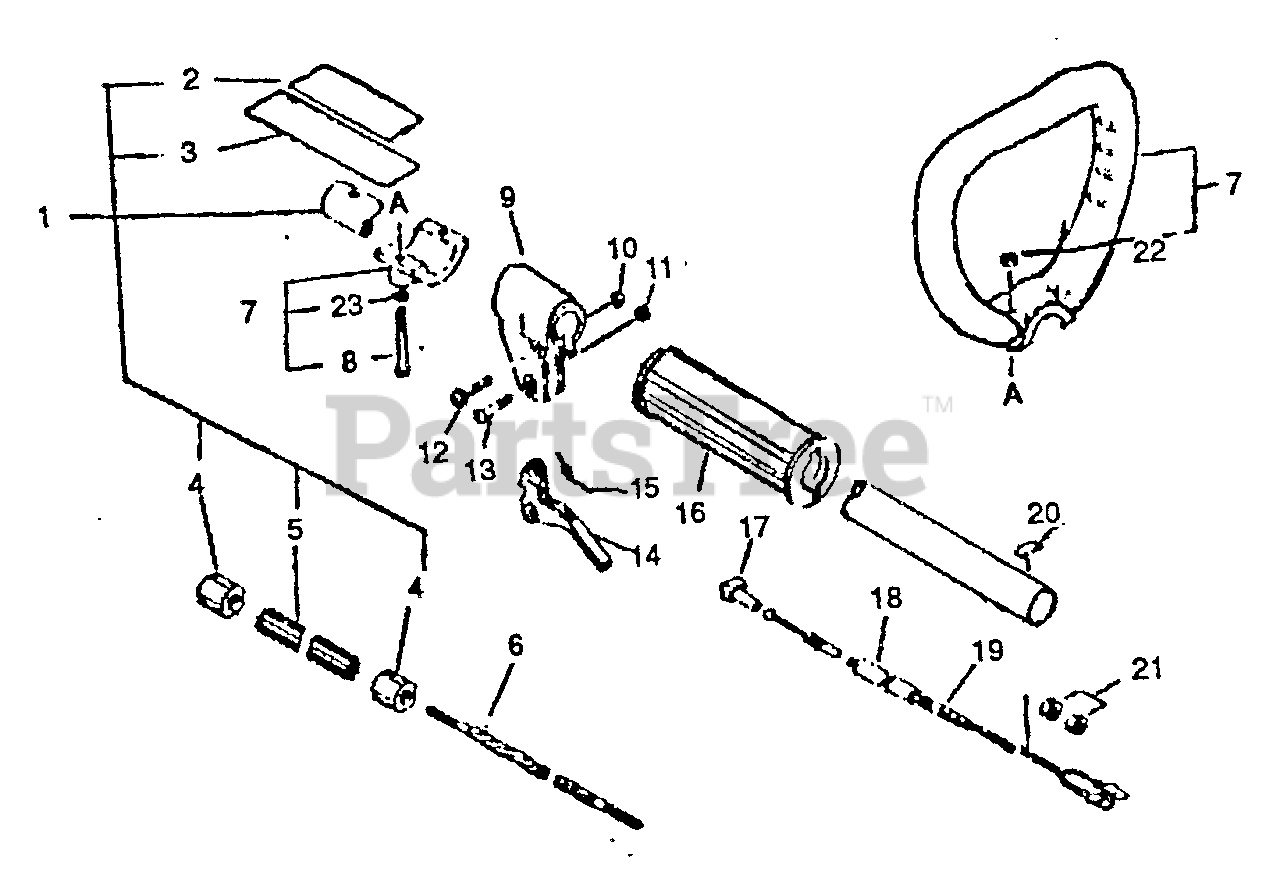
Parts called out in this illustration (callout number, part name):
1	Housing Asy, Driveshaft
2	Label, Caution
3	Label, Caution
5	Liner, Flexible
6	Shaft, Flexible
7	Handle Asy, Loop
8	Screw 5X40
9	Holder, Trigger
11	Locknut 5
12	Screw 5X30
14	Trigger, Throttle
15	Spring, Throttle Return
16	Grip, Handle
17	Holder, Throttle Wire
19	Wire, Throttle
20	Label, Caution
21	Nut 6 (3)
22	Nut 5
23	Washer 5
